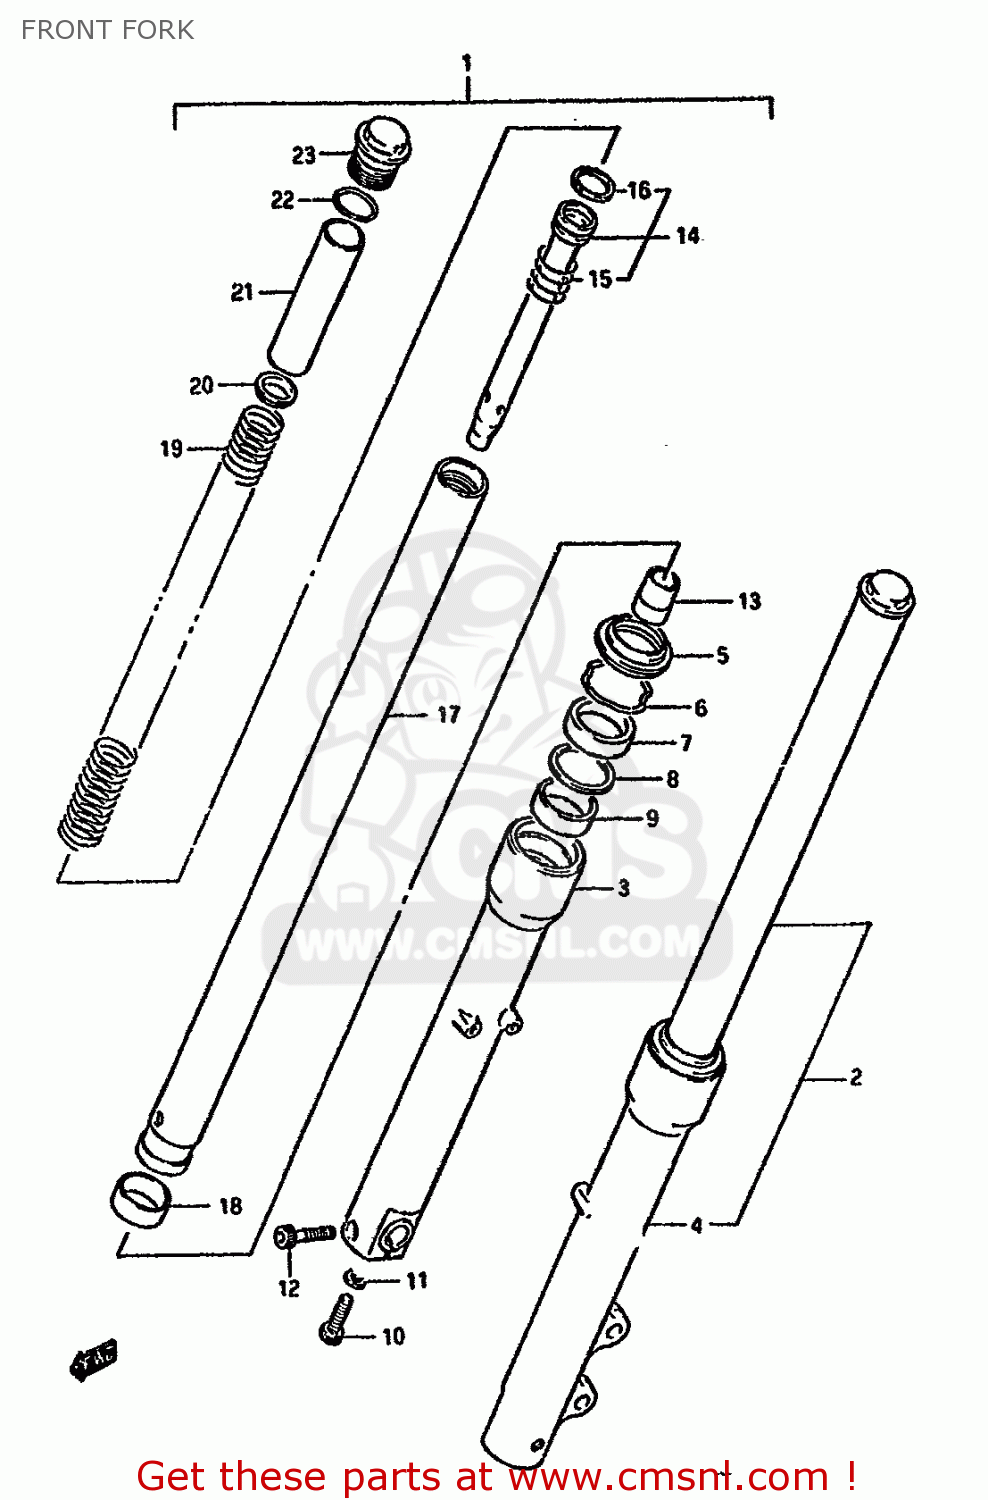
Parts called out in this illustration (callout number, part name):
1	DAMPER ASSEMBLY,RIGHT
2	DAMPER ASSEMBLY,LEFT
3	TUBE,OUTER,R
4	TUBE,OUTER,L
5	SEAL,DUST
6	RING,STOPPER
7	SEAL,OIL
8	WASHER(40X50X2.3)
9	METAL,SLIDE
10	BOLT,FORK CYLINDER(10X25)
11	GASKET (NAS)
12	BOLT
13	PIECE,OIL LOCK
14	CYLINDER
15	SPRING,REBOUND
16	RING,PISTON
17	TUBE,INNER
18	PISTON
19	SPRING
20	GUIDE,SPRING
21	SPACER
22	O RING
23	CAP
